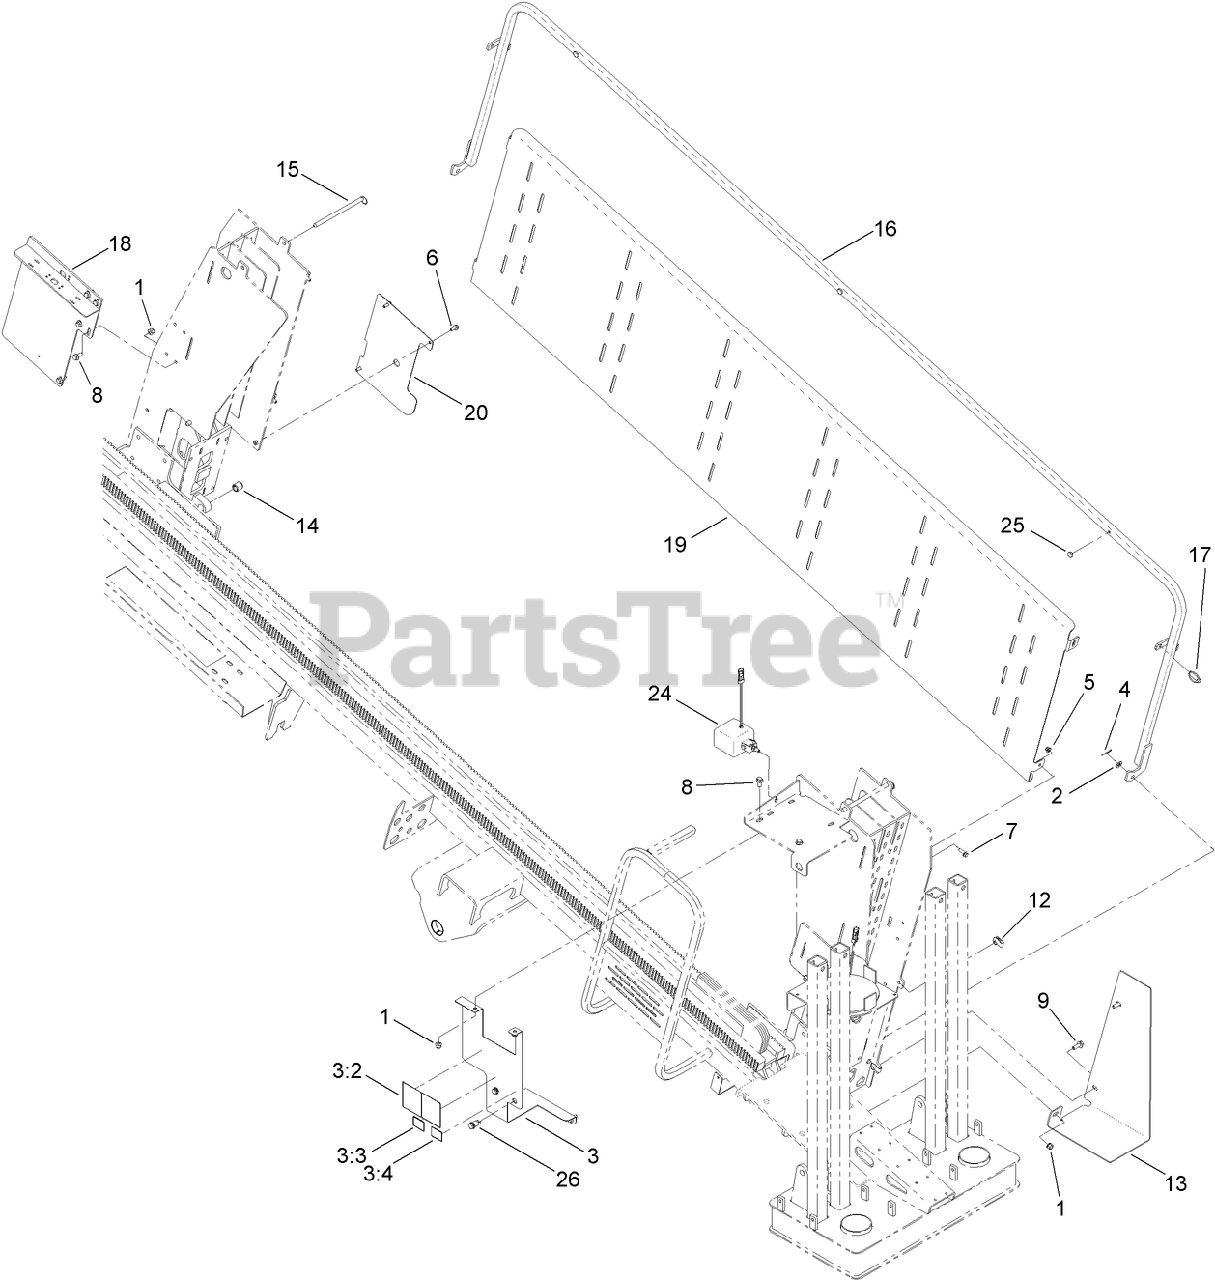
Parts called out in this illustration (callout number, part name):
1	NUT-LOCK, NI
2	WASHER-FLAT
3	GUARD PLATE ASM
3:2	DECAL-STAKEDOWN SET UP
3:3	DECAL-PIPE RETURN, CLEAR
3:4	DECAL-PIPE BREAKOUT, CLEAR
4	PIN-COTTER
5	NUT-LOCK, HHF
6	SCREW-HHF
7	SCREW-HHF
8	SCREW-HHF
9	SCREW-HHF
13	COVER-SIDE
14	BUSHING-SPRING
17	PIN-SNAP RING
18	PLATE-MOUNT, SWITCH
19	PANEL-ROD BOX
20	GUARD-ELEVATOR
24	LIGHT-WORK
25	BUMPER
26	LAMP-INDICATOR, LED
